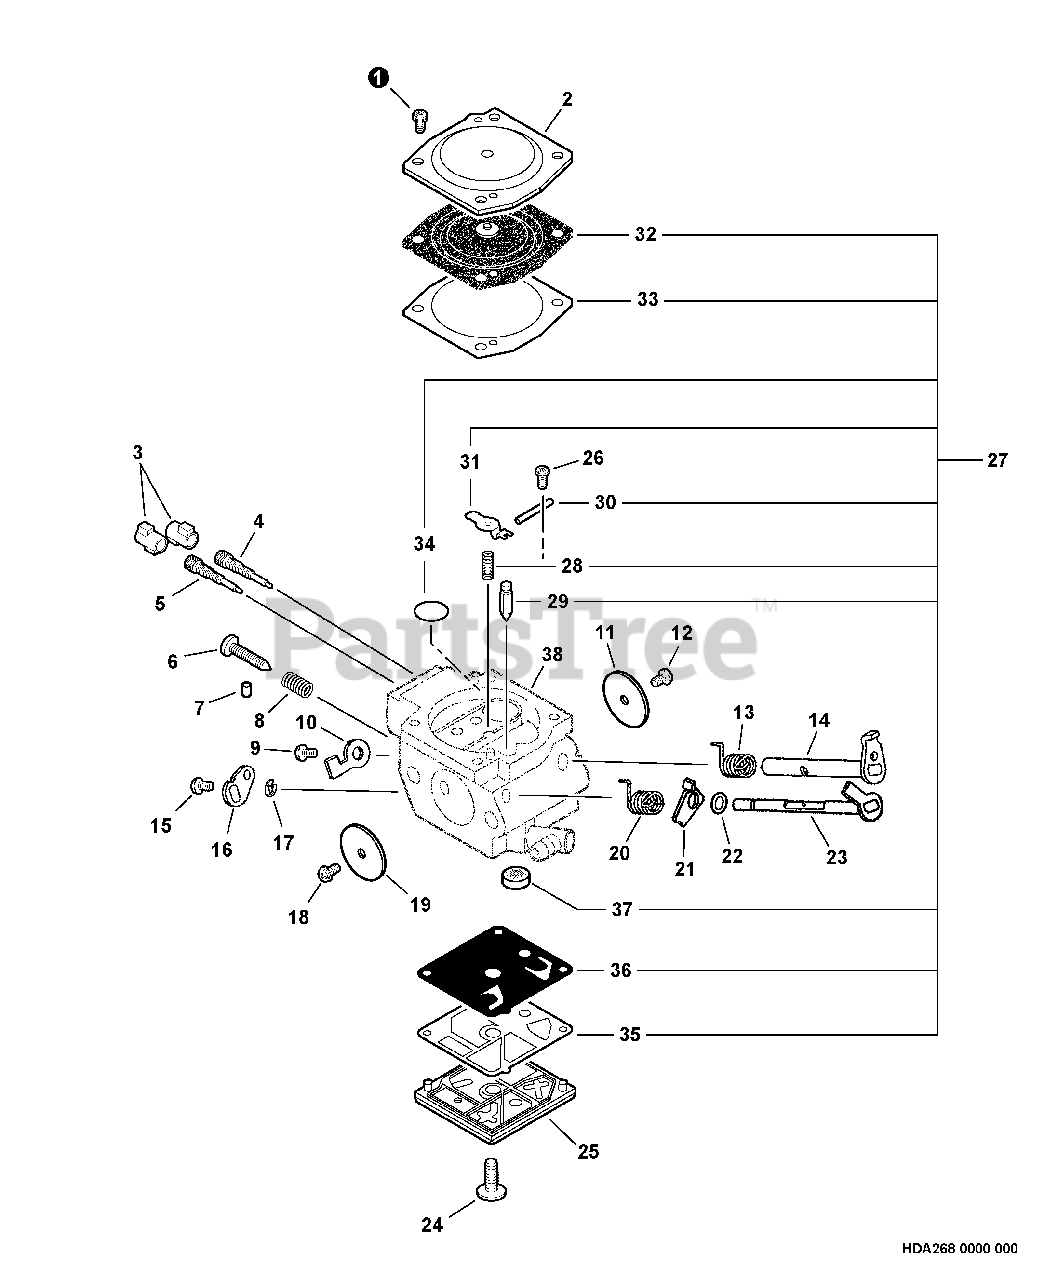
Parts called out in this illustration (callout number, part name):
2	COVER, METERING
3	CAP, LIMITER
4	NEEDLE - MIXTURE
5	NEEDLE - HIGH SPEED
6	SCREW, IDLE ADJUST
8	SPRING, IDLE ADJUST
10	STOP, THROTTLE
11	VALVE, THROTTLE
13	SPRING, THROTTLE RETURN
14	SHAFT, THROTTLE
16	LEVER, CHOKE
17	RING, RETAINING
19	VALVE, CHOKE
20	SPRING, CHOKE RETURN
21	LEVER, FAST IDLE
23	SHAFT, CHOKE
24	SCREW, PUMP COVER
25	COVER, PUMP
26	SCREW, METERING LEVER PIN
27	REPAIR KIT
28	SPRING, METERING LEVER
29	VALVE, INLET NEEDLE
30	PIN, METERING LEVER
31	LEVER, METERING
32	DIAPHRAGM, METERING
33	GASKET, METERING
34	PLUG, WELCH
35	GASKET, PUMP
36	DIAPHRAGM, PUMP
37	STRAINER
38	BODY, CARBURETOR
